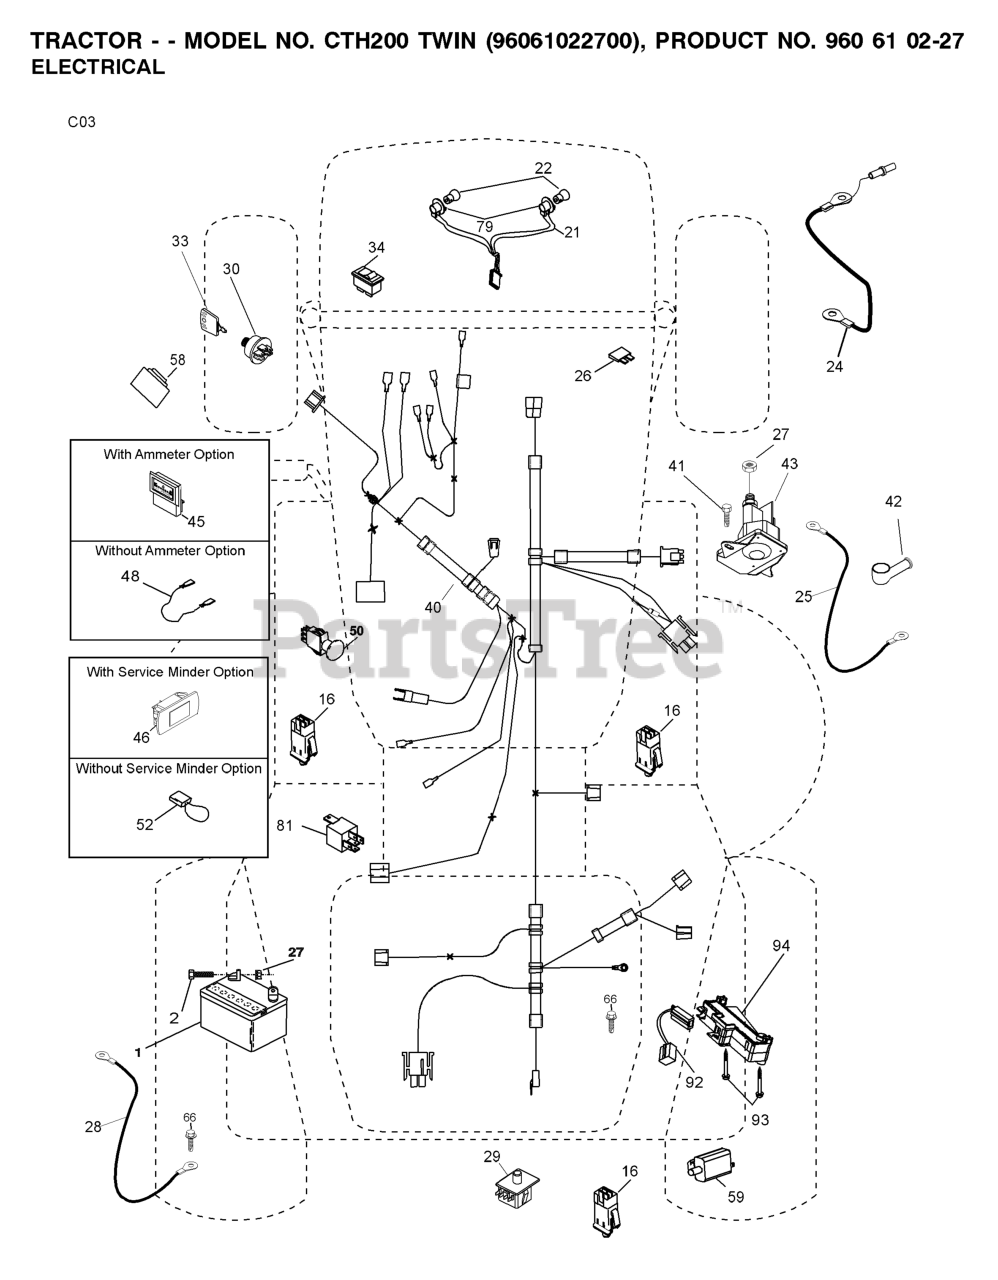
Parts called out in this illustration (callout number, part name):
1	WHEEL STEERING
2	AXLE.CAST.IRON
4	SPINDLE.WELDED.LH.16"TEX
5	SPINDLE.WELDED.RH.16"TEX
6	THRUST WASHER
9	CAP.SPINDLE.BLACK
14	WASHER, LOCK 3/8
15	NUT CROWNLOCK 3/8-24
16	SHAFT, STEERING
19	PLATE.STEER.DDL.NLT/NG
21	ADAPTER, WHEEL STNG..
22	BUSHING.ASM.STEERING.A
26	RP INSERT.CAP.WHL.STRG.HUSQ.
28	SCREW, 3/8-16X3/4
35	GEAR.SECTOR.PLATE.DDL.
45	WASHER 9/16"ID, 2 3/8"OD
51	NUT.HEX.1/2-20
53	WASHER.HARDENED
57	BRKT.UPSTOP.GT/LT.TEX
58	BOLT.SHOULDER.SECTOR.P
59	WASHER.THURST.SECTOR.S
60	NUT FLANGE LOCK 5/8-11
61	DRAGLINK.LH.BALLSTUD.D
62	DRAGLINK.RH.BALLSTUD.D
63	SCREW
64	RETAINER.CLIP.SPRING.S
66	BOLT HEX FGHD 7/16-14 X 3 SERR
67	BUSHING.PM.FRONT AXLE
68	NUT.LOCK.FLANGE.7/16
69	WASHER.1.5X.505X.118
70	BRKT.DECK.SUSPENSION.F
